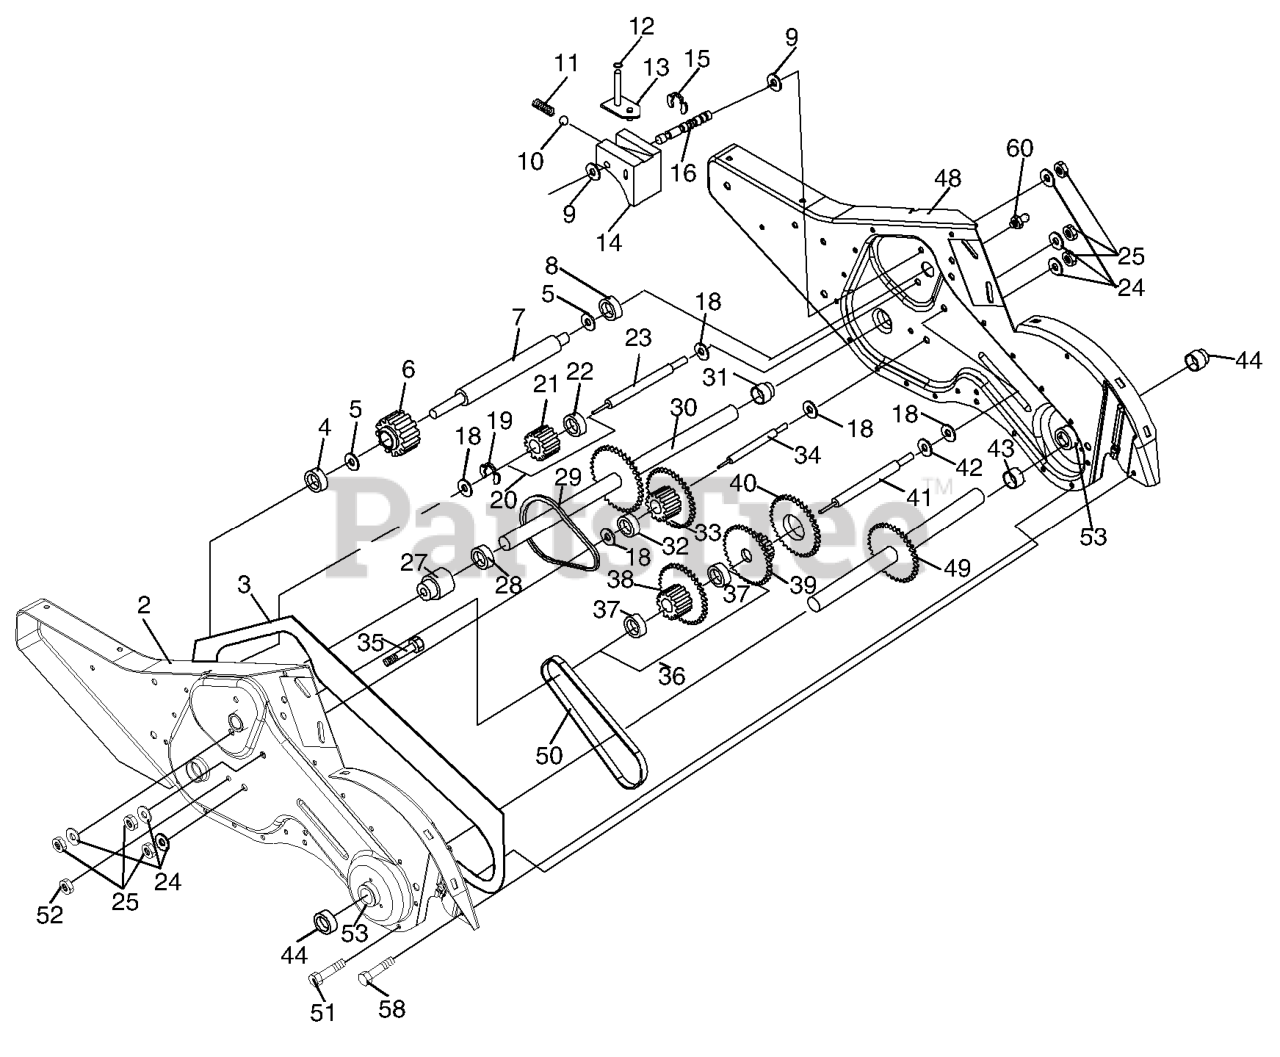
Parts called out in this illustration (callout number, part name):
1	TRANSMISSION ASM.
2	GEARCASE.ASM.CRT.LH.W/BEARING
3	GASKET
4	NEEDLE BRNG LT
5	THRUST WASHER
6	GEAR.PINION.INPUT
7	SHAFT.INPUT."D".TILLER
8	BEARING TI
9	WASHER, SEAL (2 2)
10	STEEL BALL KIT
11	SPRING-SHIFT CRT
13	BRACKET ASM.SHIFT.CRT
14	SHIFT FORK TI
16	SHAFT.SHIFTER.TILLER
20	GEAR ASSY CRT
21	GEAR-REV IDLR CRT
22	NEEDLE BEARING TI
24	LOCKWASHER
25	NUT.ASF.HEX.7/16
27	BEARING, SHAFT LH CRT
30	GROUND SHAFT ASS'Y
31	BEARING, SHAFT RH CRT
33	SPRCKT 8 GEAR CRT
34	SHAFT.SECONDARY.REDUCTION.CRT
35	SCRW WHIZ LOK CRT
36	SPROCKET.ASM.W/BEARING.TILLER
37	BEARING
38	SPROCKET, TINE
41	SHAFT.REDUCTION.TILLER
42	BRNG RACE T
44	SEAL ASM, OIL
48	GEARCASE.ASM.CRT.RH.W/BEARING
49	TINE SHAFT
50	CHAIN.TILLER
51	SCREW
52	NUT
53	KIT.BEARING.TILLER.
58	BOLT SHOULDER 1/4-20 UNC X.875
60	FITTING.GREASE.TAPERED
